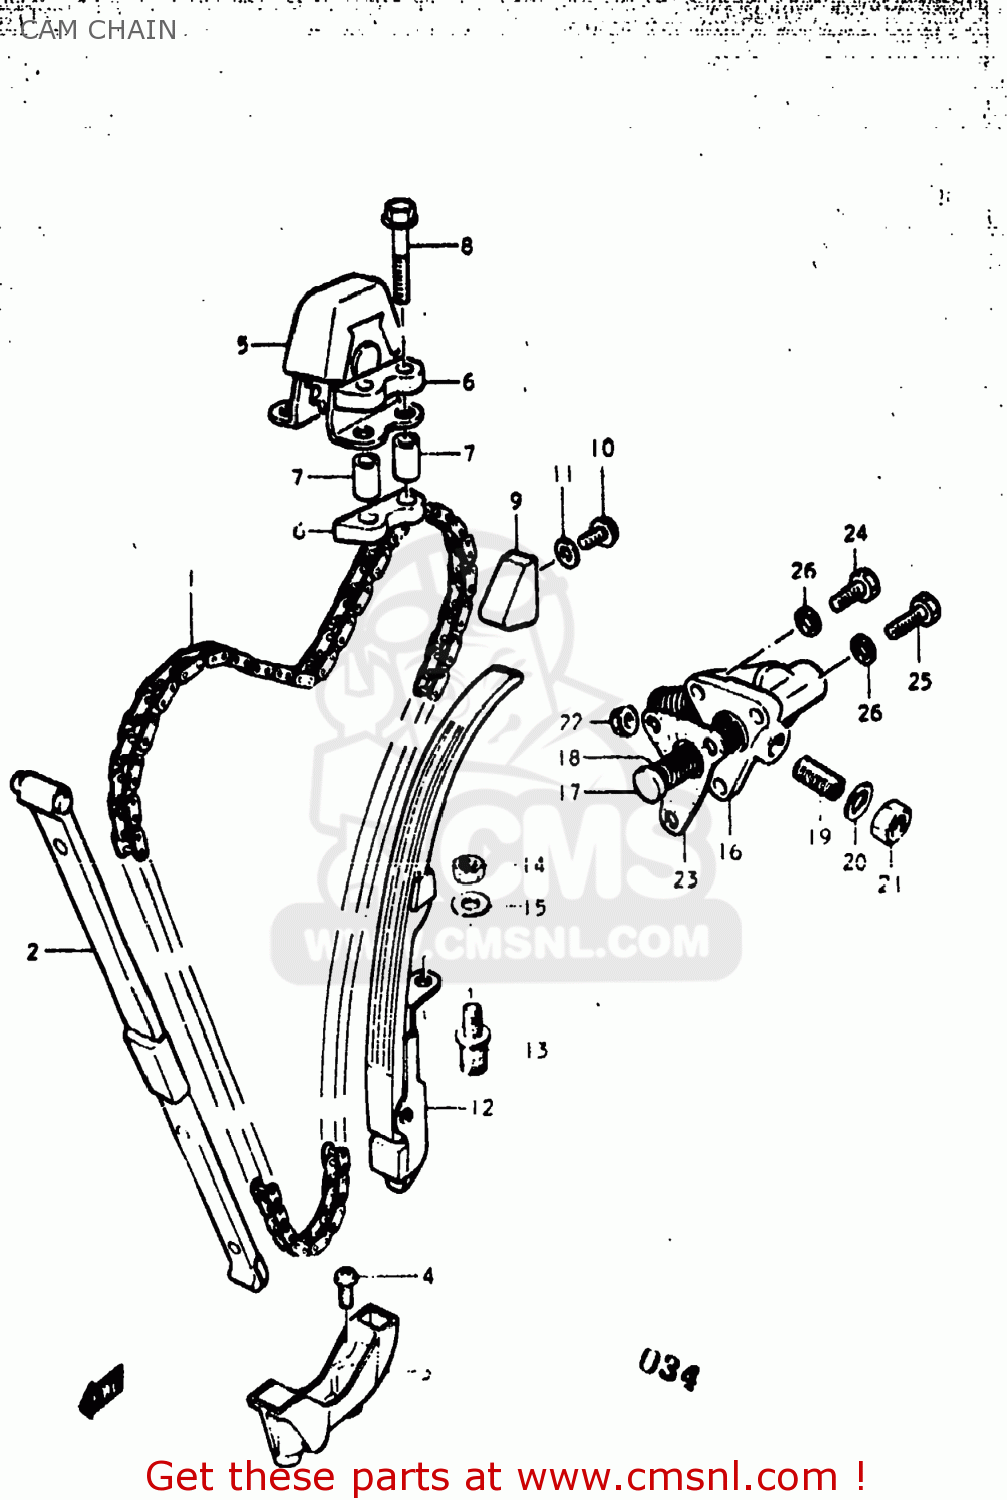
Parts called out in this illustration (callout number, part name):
1	CHAIN,CAMSHAFT DRIVE(120L)
2	GUIDE,CAM CHAIN
3	HOLDER,CAM CHAIN GUIDE
4	SCREW
5	IDLER,CAM CHAIN
6	CUSHION,IDLER
7	SPACER
8	BOLT
9	GUIDE,CAM CHAIN
10	BOLT
11	GASKET (NAS)
12	TENSIONER,CAM CHAIN
13	STUD
14	NUT
15	WASHER
16	ADJUSTER ASSEMBLY,TENSIONER
17	ROD,PUSH
18	SPRING
20	GASKET(10.5X16X1.4)
21	NUT
22	NUT
23	GASKET,TENSIONER ADJUSTER (MCA)
24	SCREW
25	SCREW
26	WASHER
